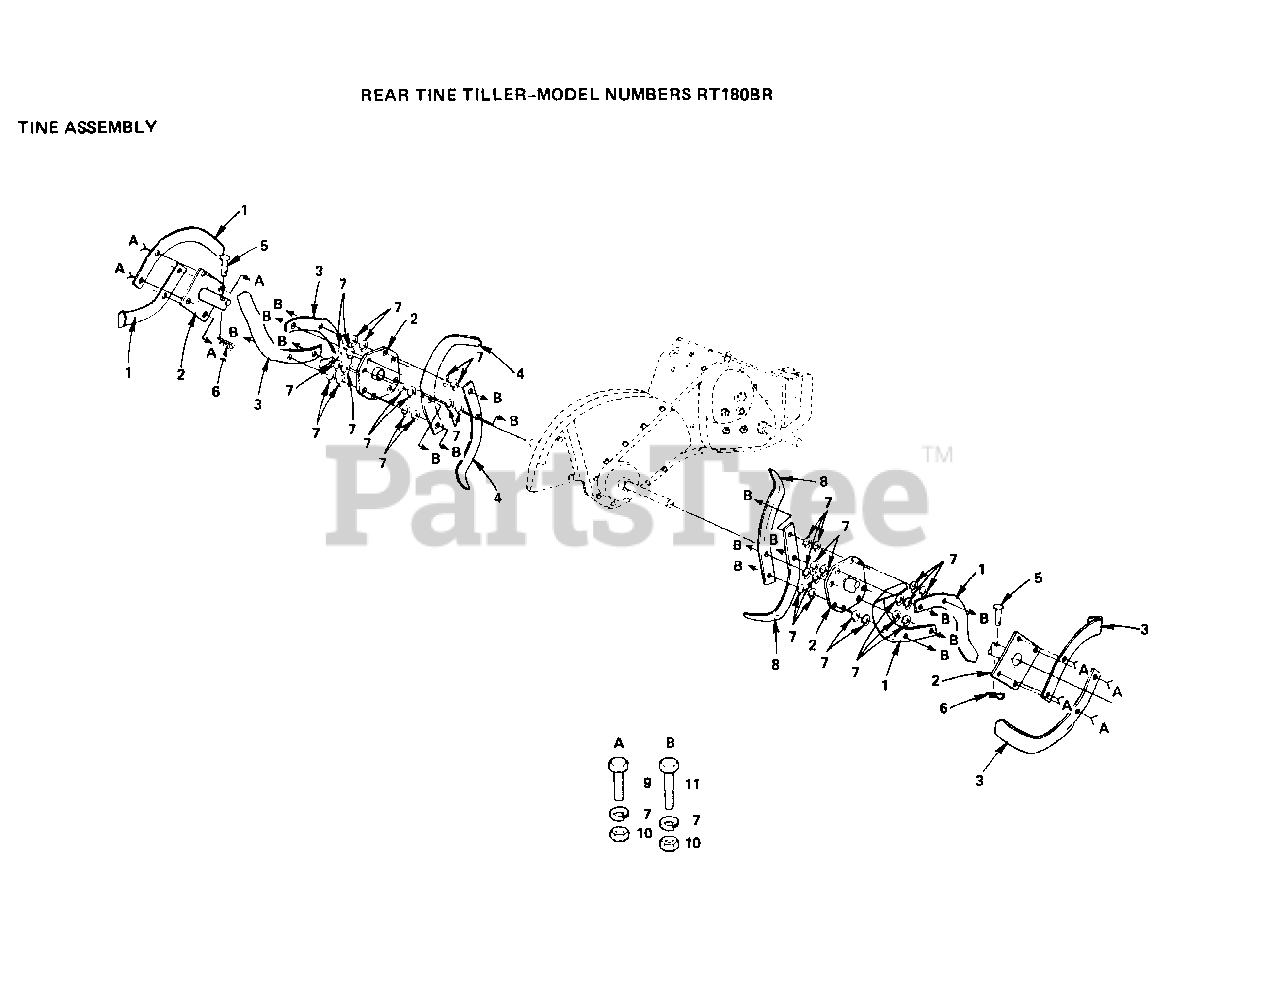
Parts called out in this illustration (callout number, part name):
2	TINE ASSY CRT
4	TINE.LH.CRT
5	RIVET.PAN HD.1.75
6	RETAINER.SPRING
7	LOCKWASHER
8	TINE RH CRT
9	BOLT
11	BOLT.3/8-24X1-1/2
